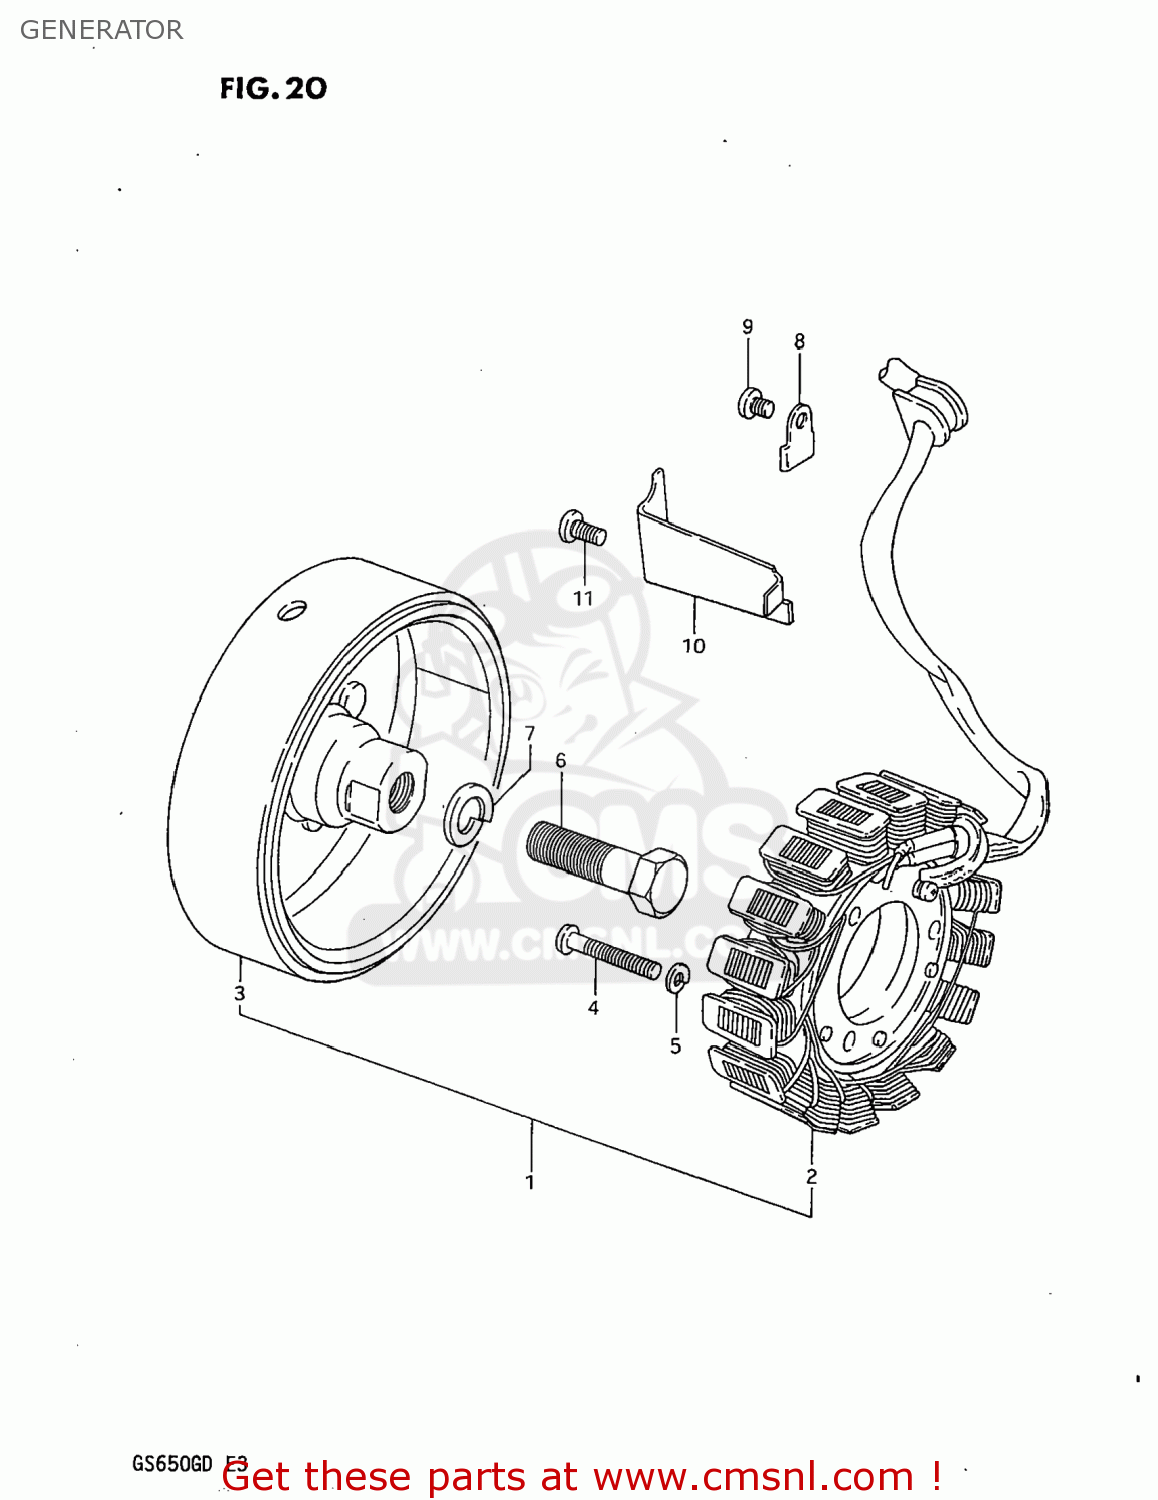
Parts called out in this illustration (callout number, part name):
1	GENERATOR ASSEMBLY
2	STATOR ASSEMBLY
3	ROTOR ASSEMBLY
4	SCREW
5	LOCK WASHER
6	BOLT 12X45
7	WASHER,LOCK 12
8	CLAMP,GENERATOR LEAD WIRE
9	SCREW
10	CLAMP,GENERATOR LEAD WIRE
11	SCREW
